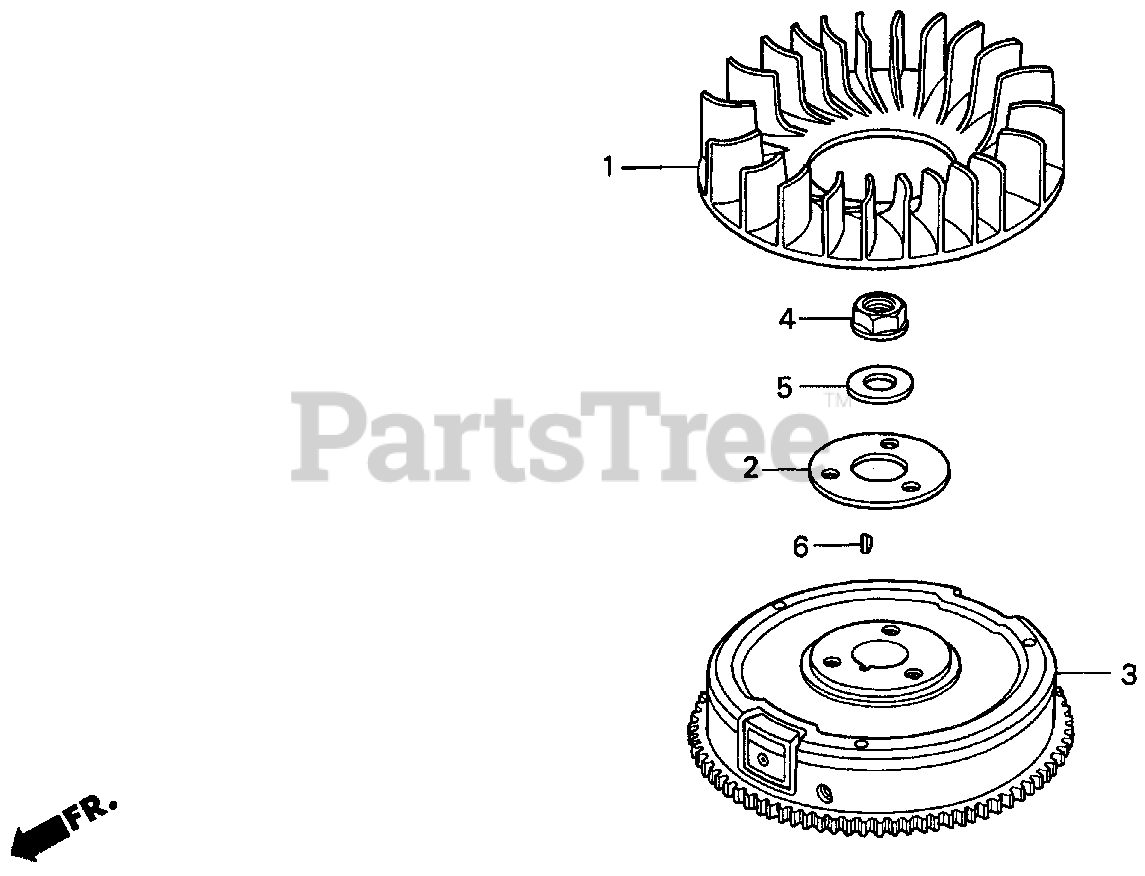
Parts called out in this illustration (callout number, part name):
1	FAN, COOLING
2	PLATE, COOLING FAN SETTING
3	FLYWHEEL
4	NUT, FLANGE (20MM)
5	WASHER (20MM)
6	KEY, SPECIAL WOODRUFF (25X18)
